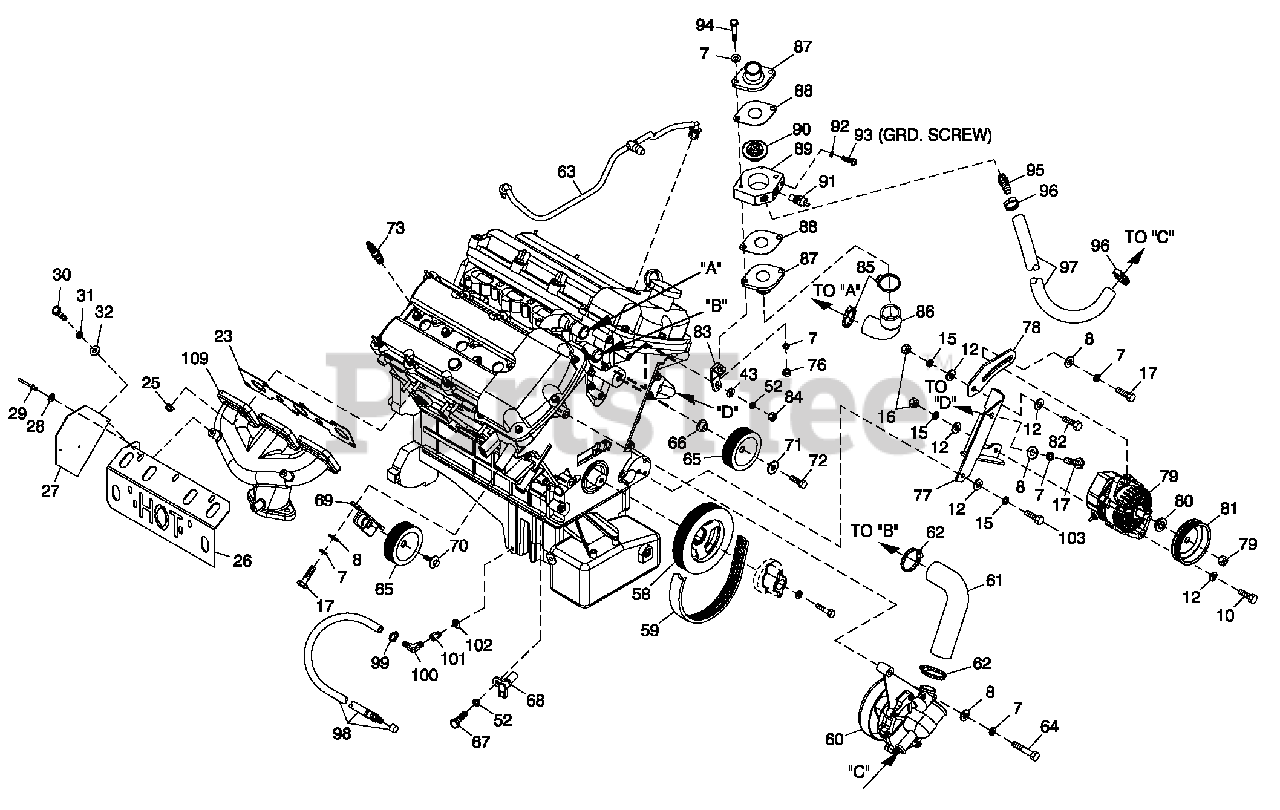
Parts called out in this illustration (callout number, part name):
1	ENGINE 3.0LRWDG14 MAKE
2	ADAPTER ENGINE
3	FLEX PLATE 2 POLE
4	SPACER FLEX PLATE
5	STARTER 12 VOLT
6	SCREW SHC M8-1.25X30G12.9
7	WASHERLOCK M8-5/16
8	WASHER FLAT 5/16-M8 ZINC
9	WASHER SHAKEPROOF EXT 7/16 STL
10	SCREW HHC M10-1.5 X 45 G8.8 FT
11	SCREW HHC M10-1.5X60 G8.8
12	WASHER FLAT 3/8-M10 ZINC
13	SCREW HHC M10-1.0X 25 G10.9
14	WASHER FLAT .45X1.00
15	WASHER LOCK M10
16	NUT HEX M10-1.5 G8 YEL CHR
17	SCREW HHC M8-1.25X 25 G8.8
18	ADAPTER OIL FILTER 3.0L
19	OIL FILTER
20	BSHG RDCR HEX 3/8 TO 1/8 GALV
21	SWITCH OIL PRESSURE 10 PSI 2 POL
22	DIP STICK OIL 3.0L
23	GASKET EXHAUST
24	MANIFOLD EXHAUST LH
25	NUT HEX FL WHIZ M8-1.25
26	HEAT SHIELD EXHAUST 3.0L
27	REFLECTIVE HEAT SHIELD 3.0L
28	WASHER FLAT #6 ZINC
29	RIVET POP .125 X .400 AL
30	SCREW HHC 1/4-20 X 1/2 SS
31	WASHER LOCK 1/4-M6 SS
32	WASHER FLAT 1/4 SS
33	OIL FILLER CAP 3.0L
34	DECAL REFER TO OWNERS MANUAL
35	BRACKET COIL
36	WASHER LOCK M5
37	NUT HEX M5-0.8 G8 CLEAR ZINC
38	SCREW HHC M5-0.8X 25 G8.8
39	MANIFOLD INTAKE LOWER 3.0L
40	PLUG EXPANSION 14 OD
41	GASKET LOWER INTAKE BOTTOM
42	SCREW HHC M6-1.0X50G8.8
43	WASHER FLAT 1/4-M6 ZINC
44	SCREW HHC M6-1.0X110G8.8
45	PLATE, INTAKE 3.0L
46	GASKET LOWER INTAKE TOP
47	MANIFOLD INTAKE UPPER
48	ASSEMBLY HOSE PCV VALVE
49	GASKET INTAKE ADAPTER
50	GASKET IDLE AIR CONTRL ACT CVR
51	COVER IAC ACTUATOR
52	WASHER LOCK M6-1/4
53	SCREW HHC M6-1.0 X 16 G8.8
54	EGR GASKET
55	COVER EGR
56	SCREW HHC M8-1.25X 20 G8.8
57	PLUG, EXPANSION 16MM
58	REWORK HARMONIC BAL 3.0L RWD
59	BELT SERPENTINE 71.04"
60	WATER PUMP 3.0L
61	HOSE WATER PUMP 3.0L
62	CLAMP HOSE #24 B1.06-2.00
63	REWORK BREATHER TUBE 3.0L
64	SCREW HHC M8-1.25X65G8.8
65	PULLEY GROOVED ENGINE IDLER
66	SPACER IDLER PULLEY 3.0L
67	SCREW HHC M6-1.0 X 20 G8.8
68	SENSOR CRANKSHAFT SPEED 3.0L
69	WELDMENT IDLER BRACKET 3.0L
70	BOLT HEX FL HD M8-1.25 X 28
71	SPACER .34 X 1.00 X .11 STL/ZC
72	SCREW HHC M8-1.25X35G8.8
73	SPARK PLUG (PLATINUM) .044 GAP
74	WASHER SHAKEPROOF EXT 5/16 STL
76	NUT HEX M8-1.25 G8 CLEAR ZINC
77	BRACKET DC ALTERNATOR LOWER
78	BRACKET TENSIONER
79	ALTERNATOR DC W/OUT PULLEY
80	SPACER DC ALTERNATOR PULLEY
81	PULLEY 132 OD DC ALTERNATOR
82	SCREW HHC M10-1.5X25G8.8
83	BRACKET THERMOSTAT 3.0L
84	NUT HEX M6X 1.0 G8 YEL CHR
85	CLAMP HOSE #28 1.32-2.25
86	HOSE UPPR RAD REAR
87	ADAPTER THERMOSTAT
88	GASKET THERMOSTAT
89	MACHINING, THERMOSTAT ADPTR
90	THERMOSTAT 195DEG
91	SWITCH HI-TEMP 245D X 3/8 NPT
92	WASHER LOCK M5
93	SCREW HHTT M5-0.8X10BP
94	SCREW HHC M8-1.25X80G8.8
95	BARBED STR 1/2NPTX 3/4
96	CLAMP HOSE #10 .56-1.06
97	HOSE COOL 3/4 ID 20R3 (22" LG)
98	HOSE OIL DRAIN ASSY 21"
99	CLAMP HOSE .38-.87
100	BARBED EL 90 3/8 NPT X 3/8
101	ADAPTER M12-1.75X 3/8 NPT
102	WASHER NYLON .50X.87X.06
103	SCREW HHC M10-1.5X35G8.8
104	RETAINER SPARK PLUG WIRE
105	RESTRICTOR PCV
106	SPARK PLUG WIRE SET
107	COIL IGNITION
108	PLUG STD PIPE 3/8 COUNTERSUNK
109	MANIFOLD EXHAUST RH
110	SCREW HHC M6-1.0 X 50 G8.8 (INCL. WITH I/N 47)
111	GASKET INTAKE MANIFOLD UP G3
